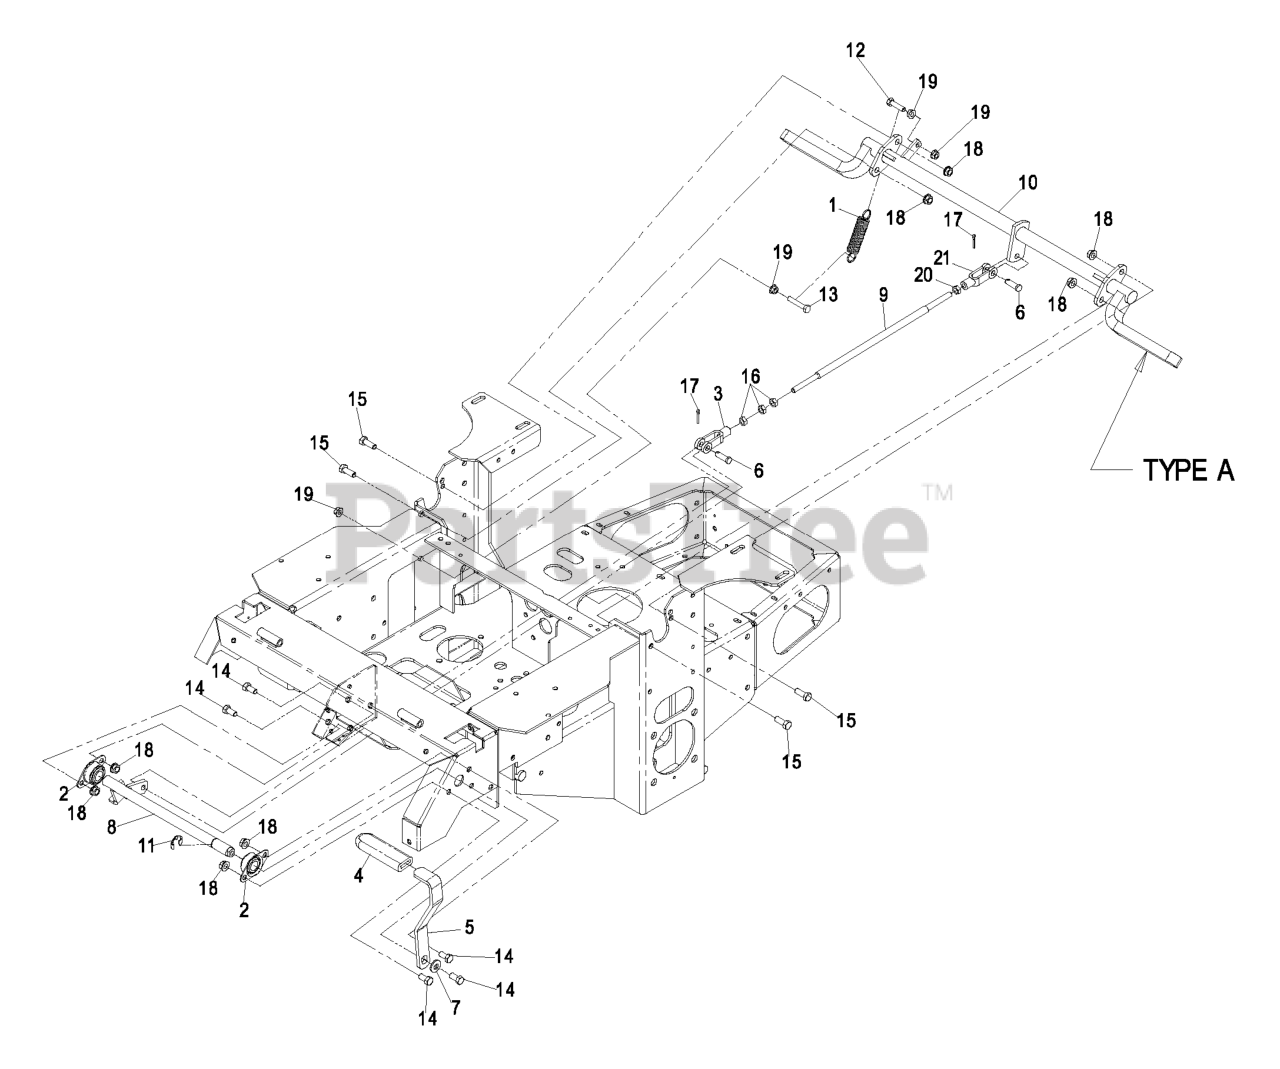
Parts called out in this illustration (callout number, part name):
1	SPRING-IDLER
2	BEARING-FLANGE, SIDE
3	YOKE-LINKAGE, BRAKE
4	GRIP-LEVER
5	ASM,BRAKE HANDLE W/ GRIP
6	PIN-CLEVIS
7	WASHER-BELLEVILLE
8	SHAFT-BRAKE, PARKING
9	LINKAGE, BRAKE (PLTD)
12	SCREW-HH
13	SCREW-HH
14	SCREW-HH
15	SCREW-HH
16	NUT-HEX
17	PIN-COTTER
18	NUT-HHF, WHIZ
20	NUT-HEX, LH
21	YOKE, LH YZ
